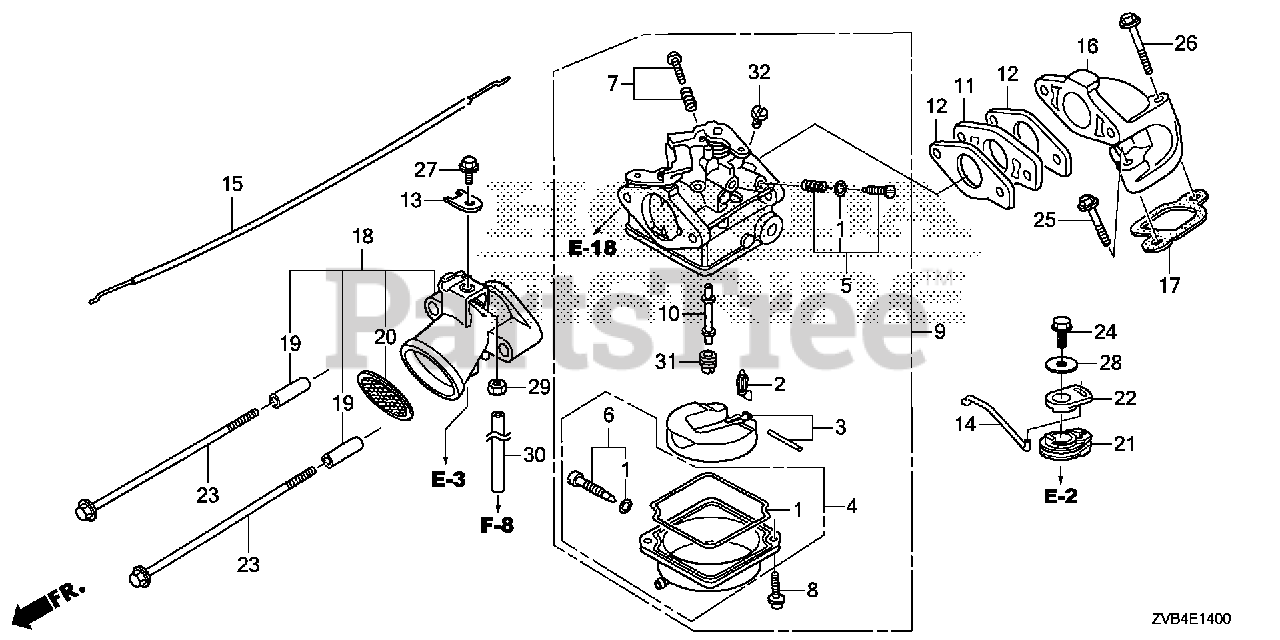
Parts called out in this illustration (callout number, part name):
1	GASKET SET
2	VALVE SET, FLOAT
4	CHAMBER SET, FLOAT
5	SCREW SET
6	SCREW SET, DRAIN (CARBURETOR NO.)
8	SCREW, PAN
9	CARBURETOR ASSY. (BC05N A)
10	NOZZLE, MAIN (CARBURETOR NO.)
11	INSULATOR, CARBURETOR
12	GASKET, CARBURETOR
13	HOLDER, CABLE
14	ROD, THROTTLE
15	CABLE, CHOKE
16	MANIFOLD, IN.
17	GASKET, IN. MANIFOLD
18	GUIDE, AIR
19	COLLAR, DISTANCE
20	TRAP, FLAME
21	ARM A, THROTTLE
22	ARM B, THROTTLE
23	BOLT, FLANGE (6X102)
24	BOLT, FLANGE (6X12)
25	BOLT, FLANGE (6X28)
26	BOLT, FLANGE (6X40)
27	BOLT, FLANGE (6X12)
28	WASHER, PLAIN (6MM)
29	NUT, HEX. (6MM)
30	BULK HOSE, VINYL (4X7X8000) (95003-07(95003-07001-60M) (CARBURETOR NO.)
31	JET, MAIN (#65) Use from Engine SN BE40A G.
31	JET, MAIN (#70) (CARBURETOR NO.)
31	JET, MAIN (#72) (CARBURETOR NO.)
